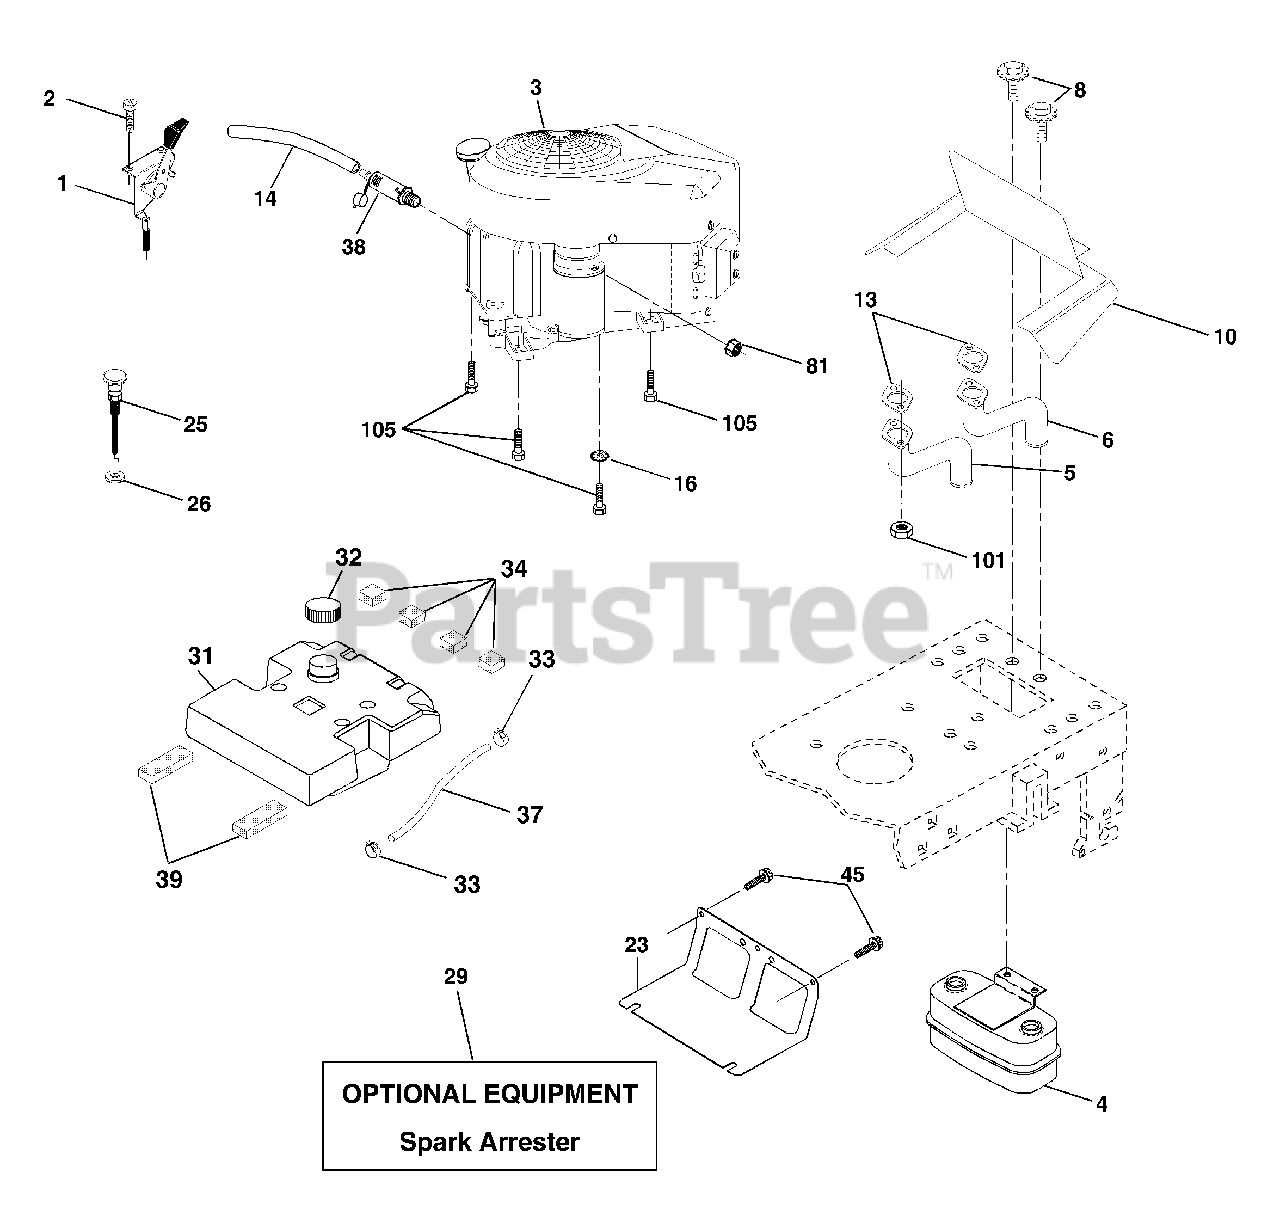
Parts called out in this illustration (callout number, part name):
1	Control Throt Flg
2	Screw Hex Thd Cut 1/4-20 x 1/2
4	Muffler Asm Twin Lo-Tone
5	Exhaust Tube
6	Exhaust Tube
8	Bolt 5/16-18unc x 3/4 W/Sems
10	Shield Browning
13	Gasket Muffler
14	Tube Drain Oil Easy
16	Washer Lock Ext Tooth 3/8
23	Shield Browning
25	Choke Control
26	Nut, Keps 3/8-24 Unf
29	Kit Spark Arrestor (Flat Scrn)
31	Tank Fuel 3 50 Rear
32	Cap Asm Fuel
33	Clamp Hose Blk
34	Pad, Spacer
37	Line Fuel
38	Plug Drain Oil
39	Pad, Idler
45	Screw Hexwsh Thdr 3/8-16 x 3/4
81	Nut Keps Hex 1/4-20 Unc
101	Nut Flange M8-1.25
105	Screw 3/8-16 x 1
